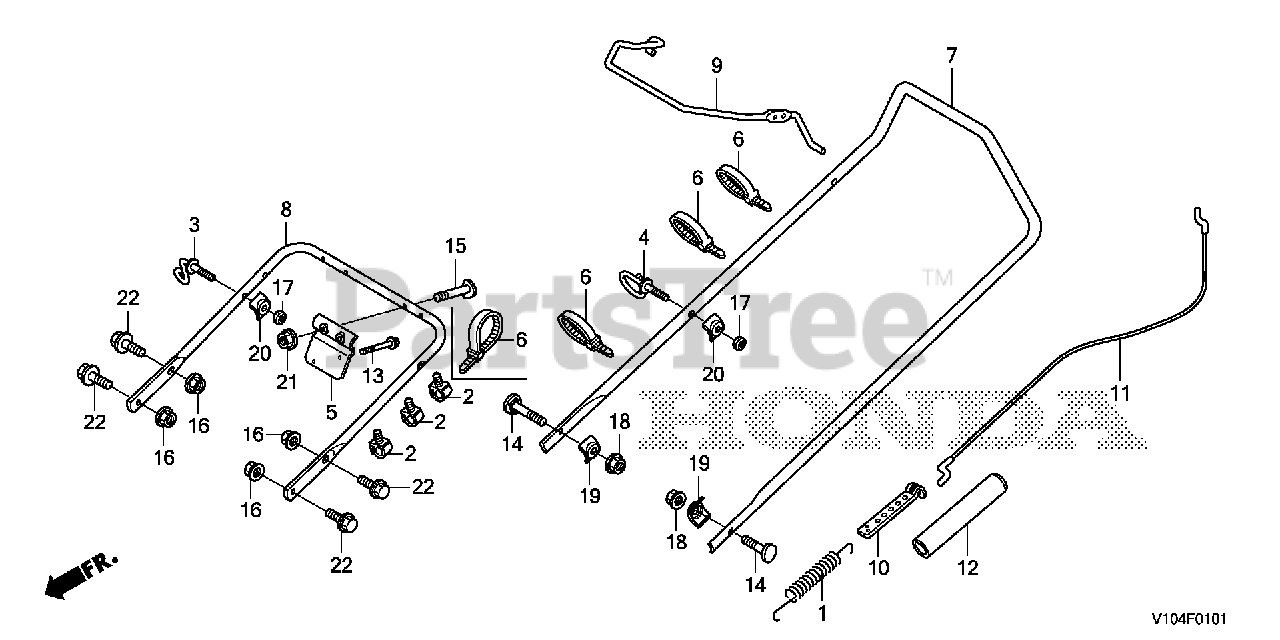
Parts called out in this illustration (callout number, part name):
1	SPRING, BELT TENSIONER
2	HOLDER, WIRE
3	HOLDER, ROPE
4	GUIDE, ROPE
5	BRACKET, SWITCH BOX
6	TIE, CABLE (157.5MM)
7	PIPE, HANDLE (UPPER)
8	PIPE, HANDLE (LOWER)
9	LEVER, CLUTCH
10	PLATE, ADJUSTING
11	CABLE, CLUTCH
12	BOOT, CLUTCH CABLE
13	BOLT, SPECIAL
14	BOLT, HANDLE HOLDER
15	BOLT, HANDLE HOLDER
16	NUT, SELF-LOCK (8MM)
16	NUT, FLANGE (8MM)
17	NUT, NYLON LOCK (6MM)
18	NUT, FLANGE (8MM)
19	WASHER, FRAME JOINT
20	WASHER, FRAME JOINT
21	NUT, FLANGE (8MM)
22	BOLT, FLANGE (8X20) Use up to Engine SN 1609606.
